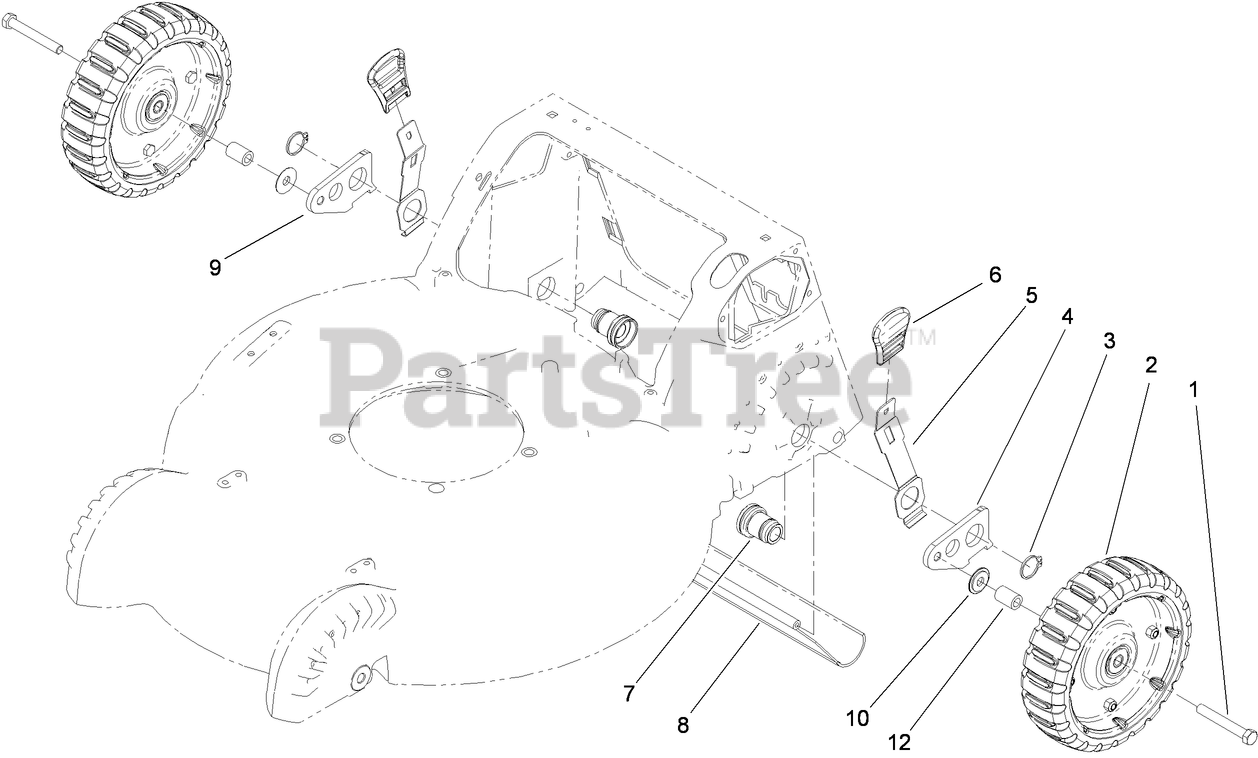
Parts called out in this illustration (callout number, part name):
1	SCREW-HH
2	8 INCH WHEEL ASM
3	RING-RETAINING
4	ARM-REAR PIVOT, LH
5	ARM-SPRING, REAR
6	Knob-Lever, HOC
7	RETAINER-BEARING
8	SHIELD-TRAILING
9	ARM-REAR PIVOT, RH
10	WASHER-STEPPED
12	SPACER
